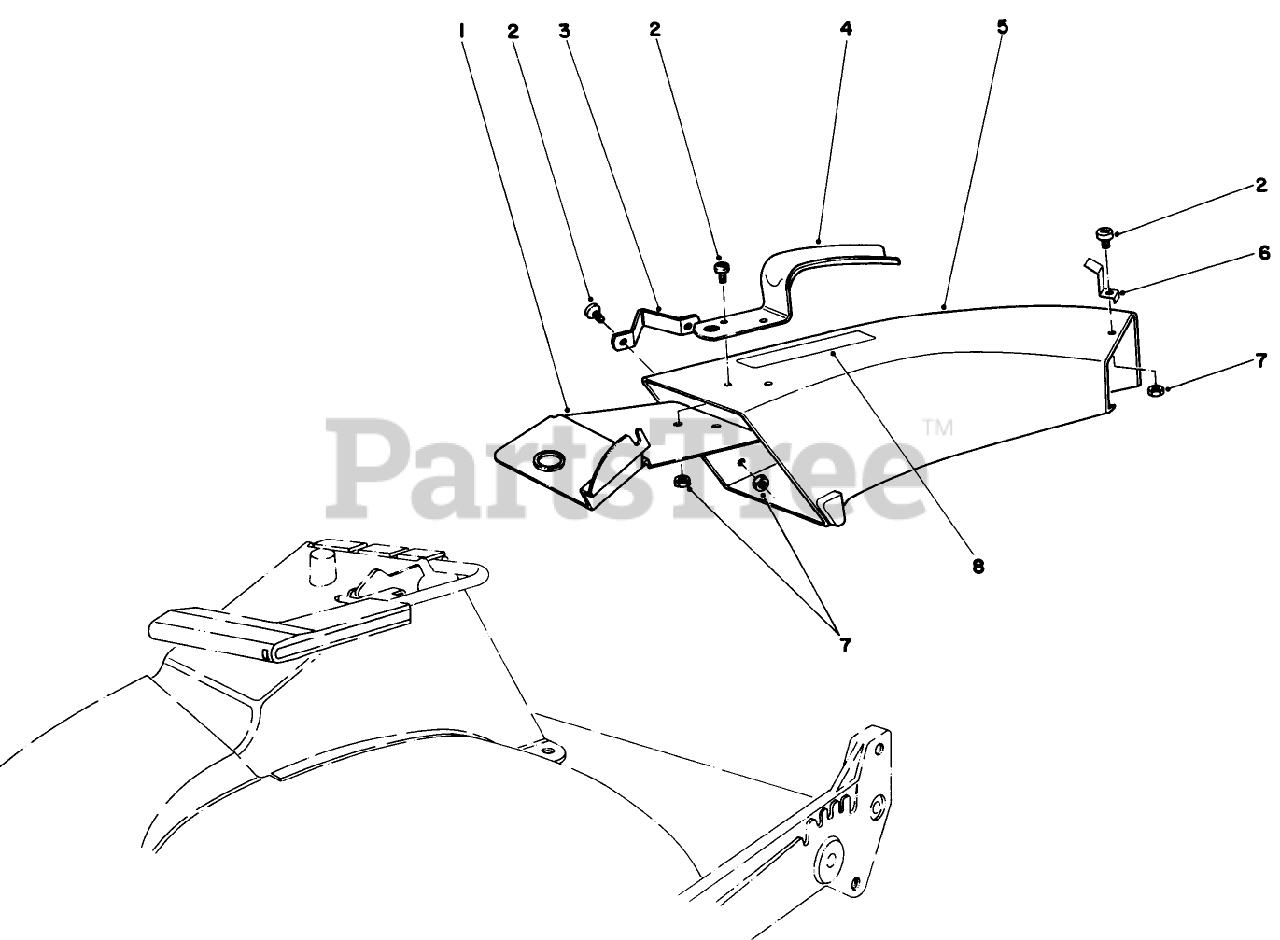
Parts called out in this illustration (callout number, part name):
2	10-24 X 5/8 PAN HD MS
4	CHUTE HANDLE
5	ORDER 59168 W.G.#
7	NUT-LOCK, NI
